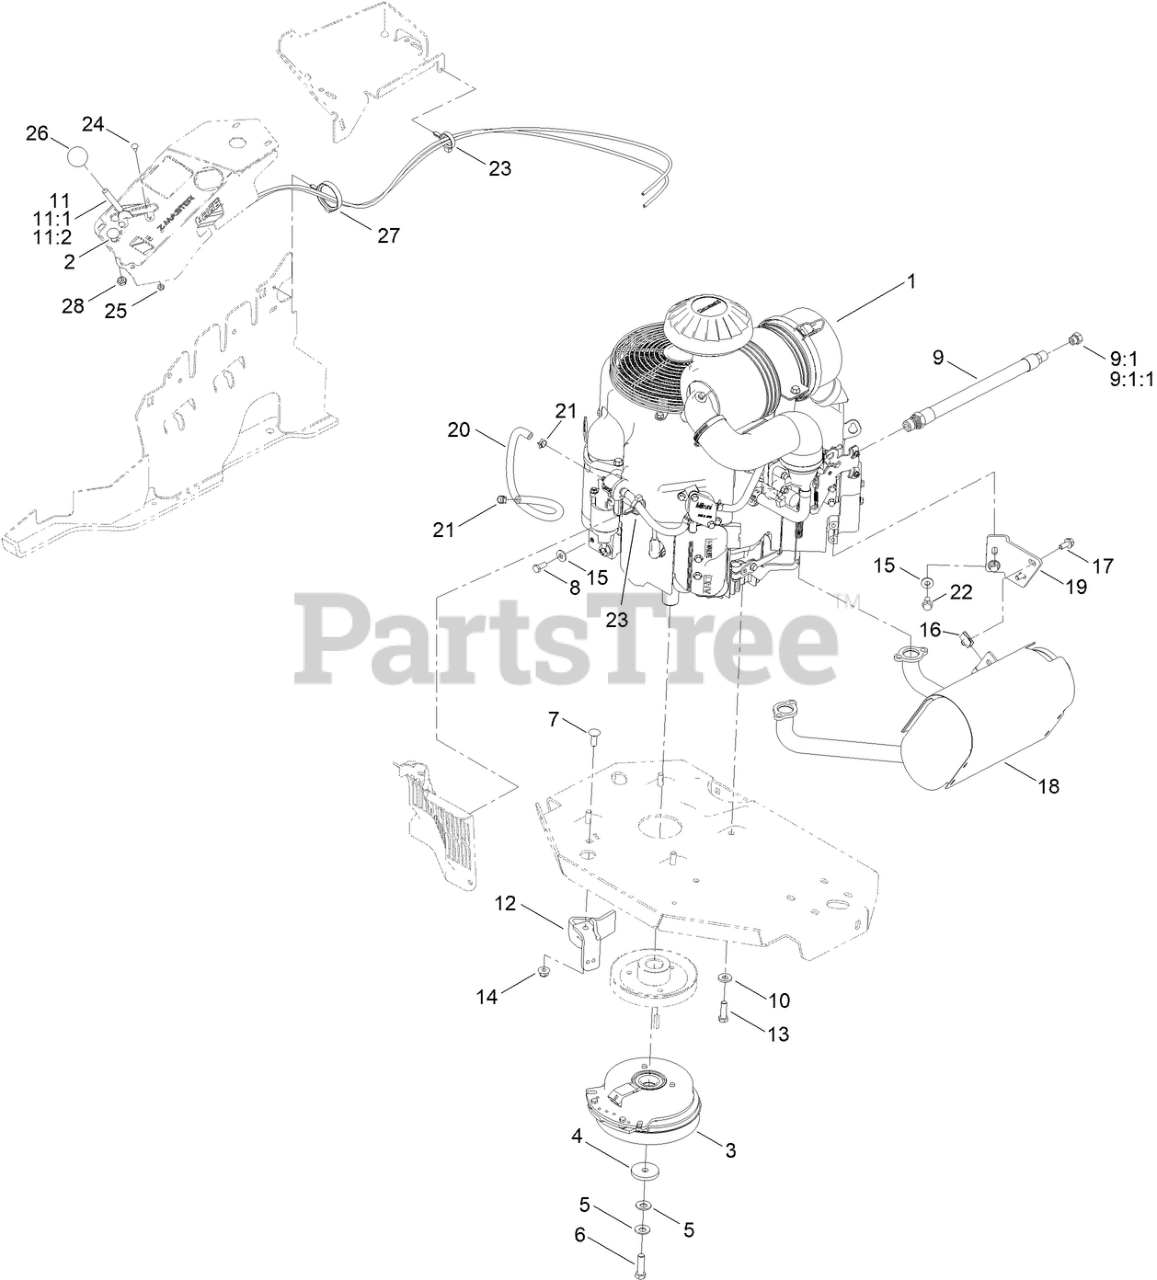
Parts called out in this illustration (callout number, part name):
2	CONTROL-CHOKE
3	CLUTCH KIT
4	WASHER-CLUTCH
5	WASHER-SPRING
6	SCREW-HH, W/LOCTITE
7	SCREW-CARR
8	SCREW-HH
9	ENGINE OIL DRAIN HOSE ASM
9:1	PLUG-HH
9:1:1	O-RING
10	WASHER-BELLEVILLE
11	THROTTLE CONTROL ASM
11:1	LEVER-THROTTLE
12	CLUTCH-ANCHOR
13	SCREW-HH
14	NUT-HF, NI
15	WASHER-SPRING
16	NUT-U
17	SCREW-HHF
18	KIT, MUFFLER
19	BRACKET-MUFFLER
20	HOSE-FUEL
21	CLAMP-HOSE
22	SCREW-HHF
23	CLAMP-HOSE
24	BOLT-CARR
25	NUT-LOCK, NI
26	KNOB-BALL
27	CLAMP-HARNESS
28	NUT-HJ
